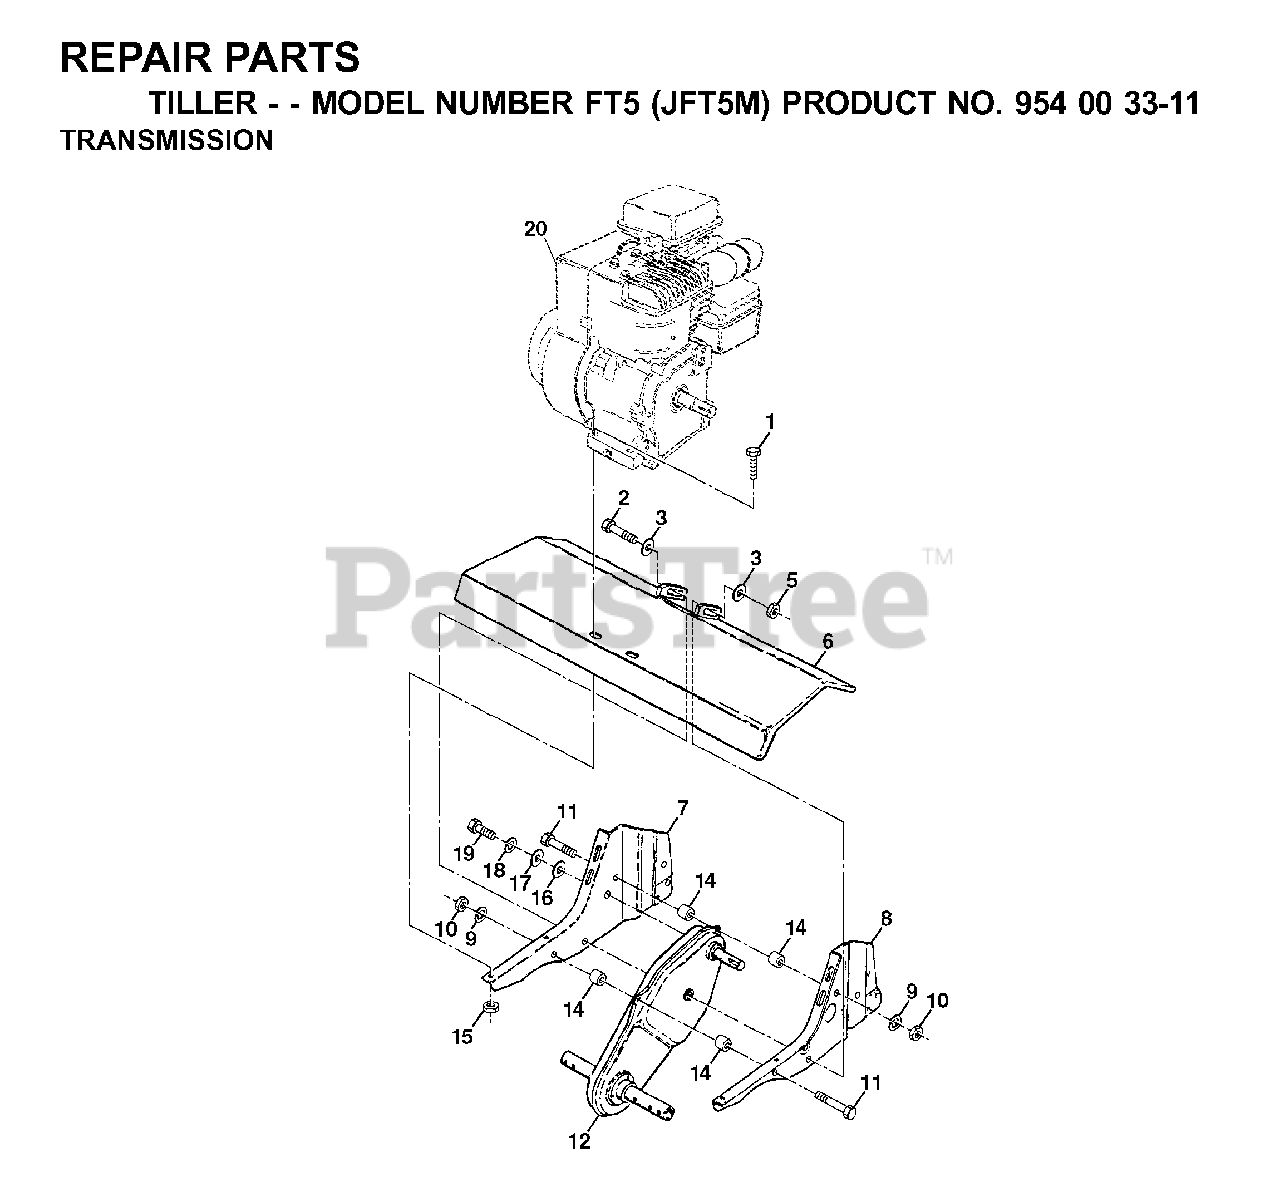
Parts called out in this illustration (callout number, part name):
1	BOLT
3	WASHER
5	NUT
9	LOCKWASHER
11	BOLT
12	TRANSMISSION.ASM.W/1".D-SHAFT
15	NUT
18	LOCKWASHER
